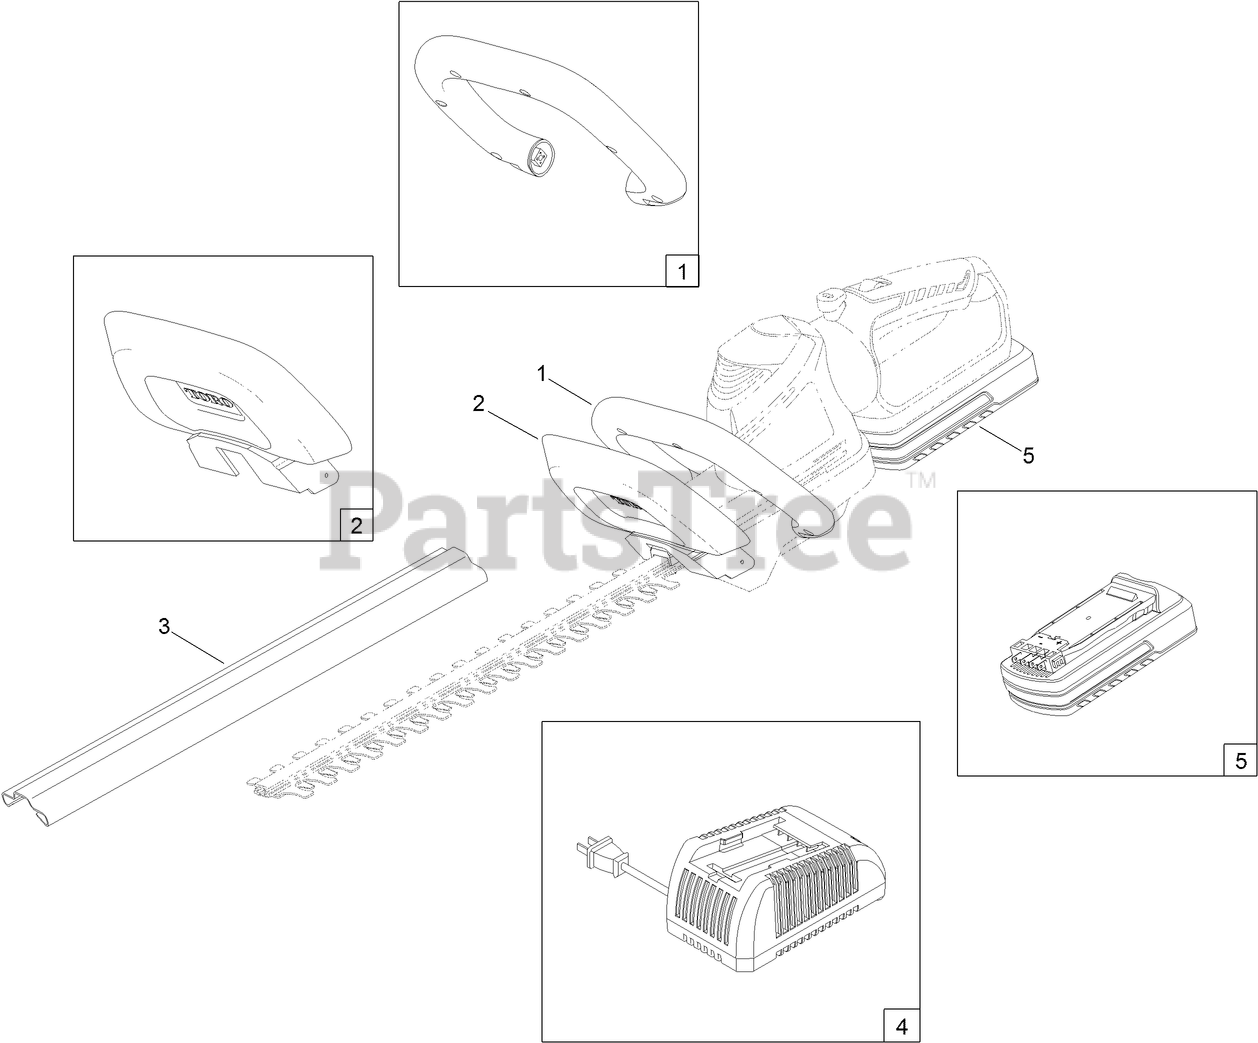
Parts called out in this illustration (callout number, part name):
1	HANDLE-ASSIST
2	GUARD-TRIMMER, HEDGE
3	GUARD-TRIMMER
4	CHARGER-20V MAX, LI ION
5	BATTERY-LI ION, 20V MAX
